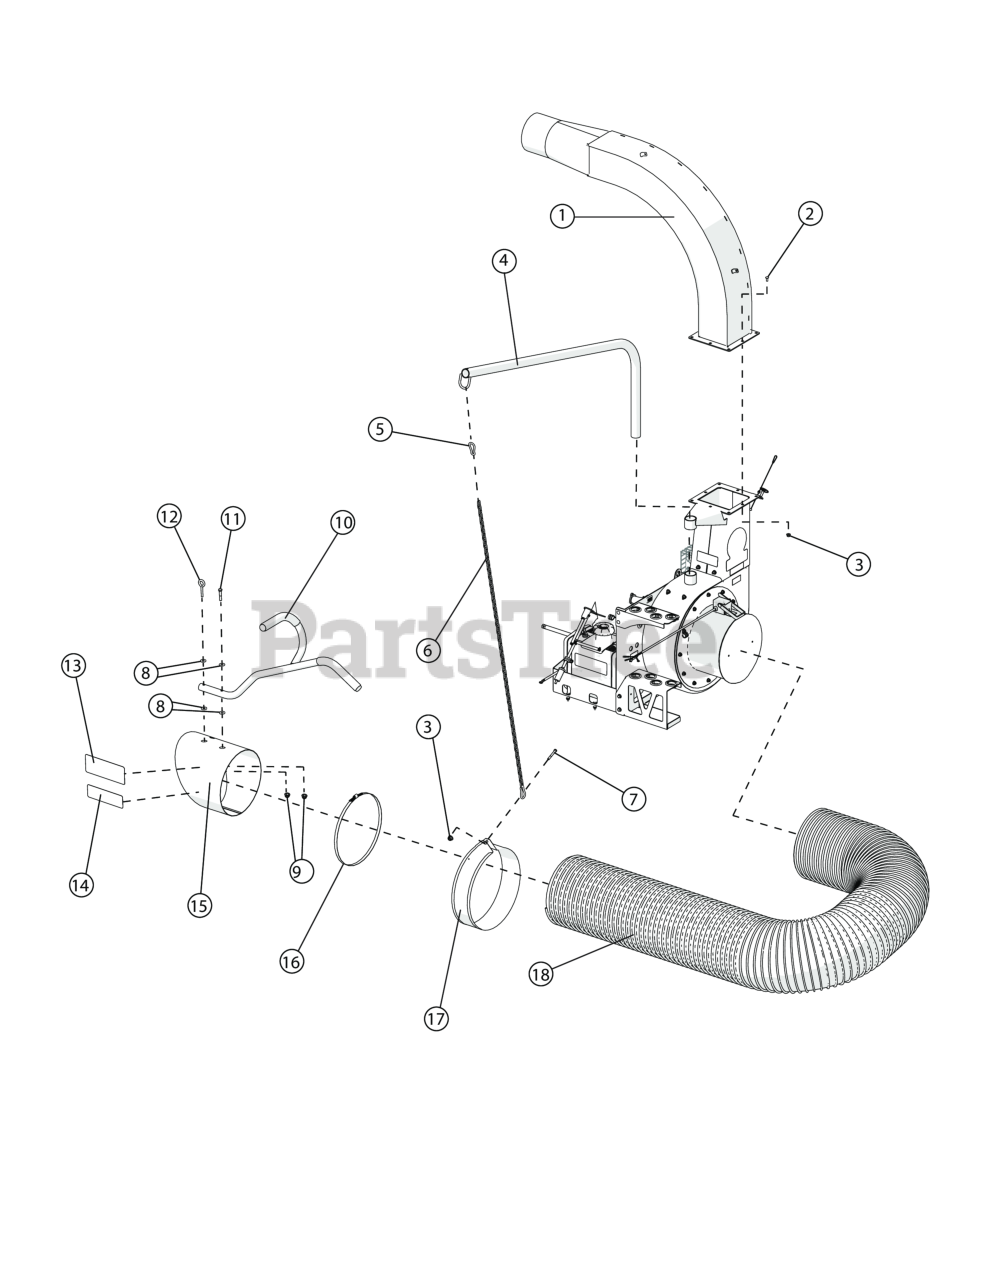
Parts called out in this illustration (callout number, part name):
1	KIT, SQUARE ELBOW DL2901/3701
2	BOLT CARRAIGE 3/8-16 X 1" ZP
3	NUT-HEX-NYLK, FLG .375"-16 ZP
4	SEE: 791117-S
5	HOOK, SNAP SAFETY 5/16" ZP
6	CHAIN 73 LINKS DL
7	SCREWCAP 3/8"-16X3" HCS ZP
8	WASHER 3/8"FC7/16"X1"X5/64"
9	NUT LOCK 3/8"-16 HEX
10	SEE: 791116-S
11	SCREWCAP 3/8"-16X2" HCS ZP
12	BOLT EYE G-2 3/8" X 2"
13	LABEL WARNING ENGINE OVERHEAT
14	LABEL WARNING HOSE TRAY QL23
15	NOZZLE INTAKE FORMED 12"
16	SEE: 790150-01
17	BAND HOSE BOOM 12" FORMED
18	HOSE INTAKE 12"X 10' (SEE ACCESSORY PRICE LIST ITEM 791034-S)
